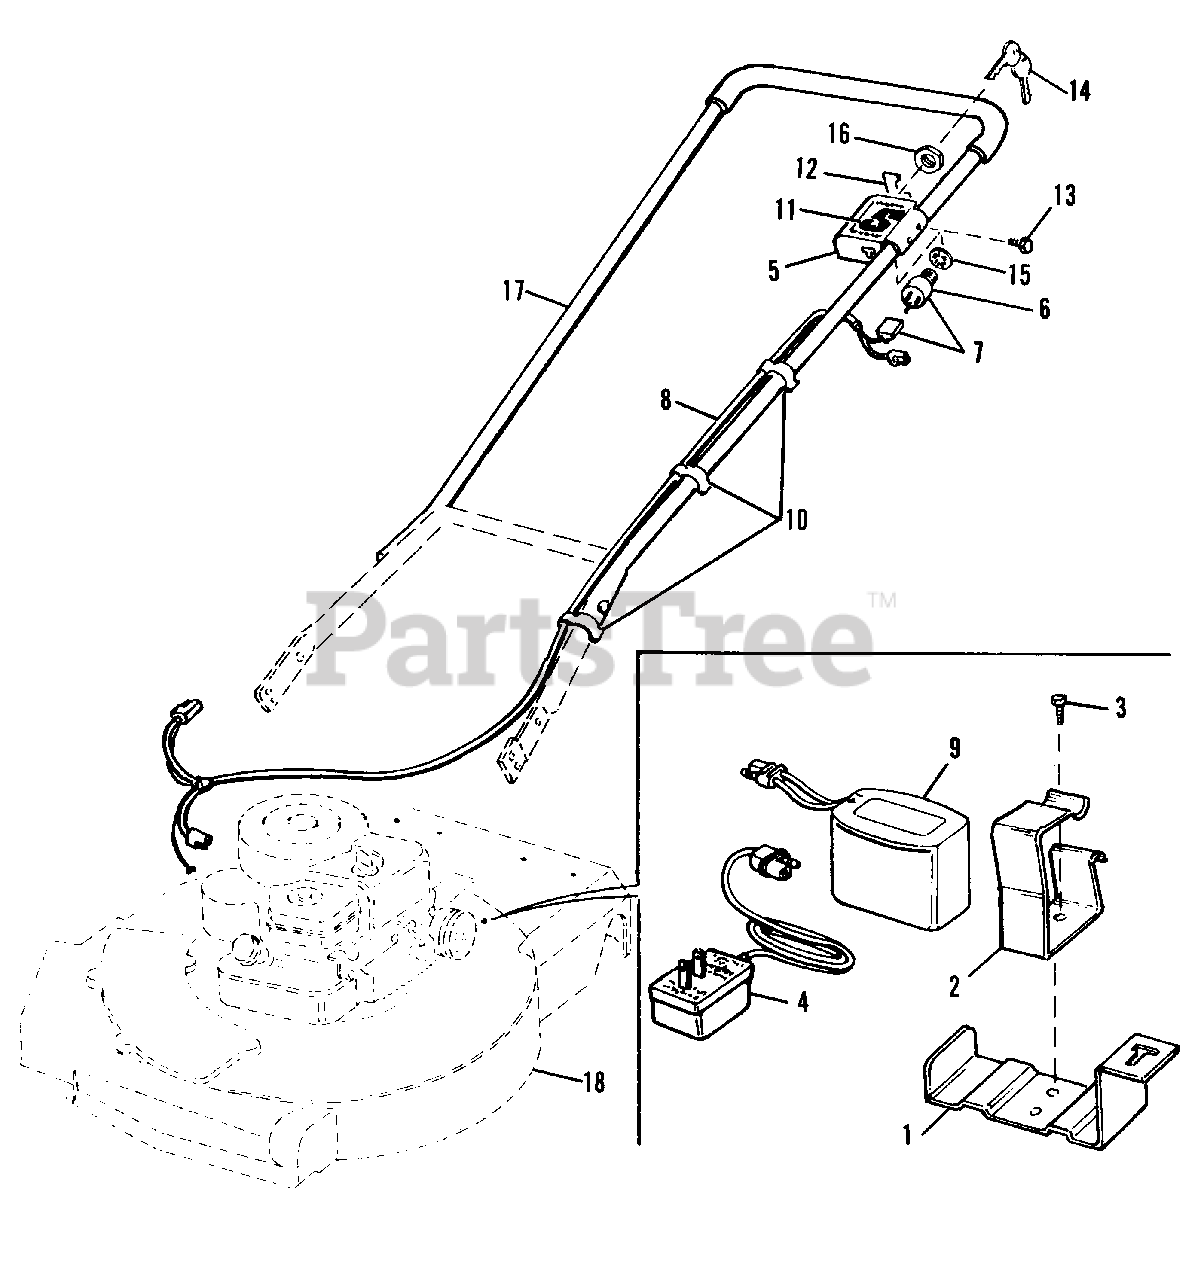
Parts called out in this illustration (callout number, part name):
1	SUPPORT, Battery
2	CLIP, Spring, Battery
3	SCREW, Thd. Form, 10-24 x 3/8
4	CHARGER, Battery
5	BRACKET, Switch Mounting
6	SWITCH, Key
7	SWITCH & HARNESS ASSY
8	HARNESS ASSY
9	BATTERY ASSY
10	CLAMP, Cable, Handle
11	FILM, Simpli-Start
12	FILM, Ignition
13	SCREW,Thd. Form. 1/4-20 x 3/8
14	KEY & RING ASSY
15	LOCKWASHER, Inter. Tooth, 9/16
16	NUT, Hex Special
17	HANDLE, Upper
18	HOUSING, 19"
